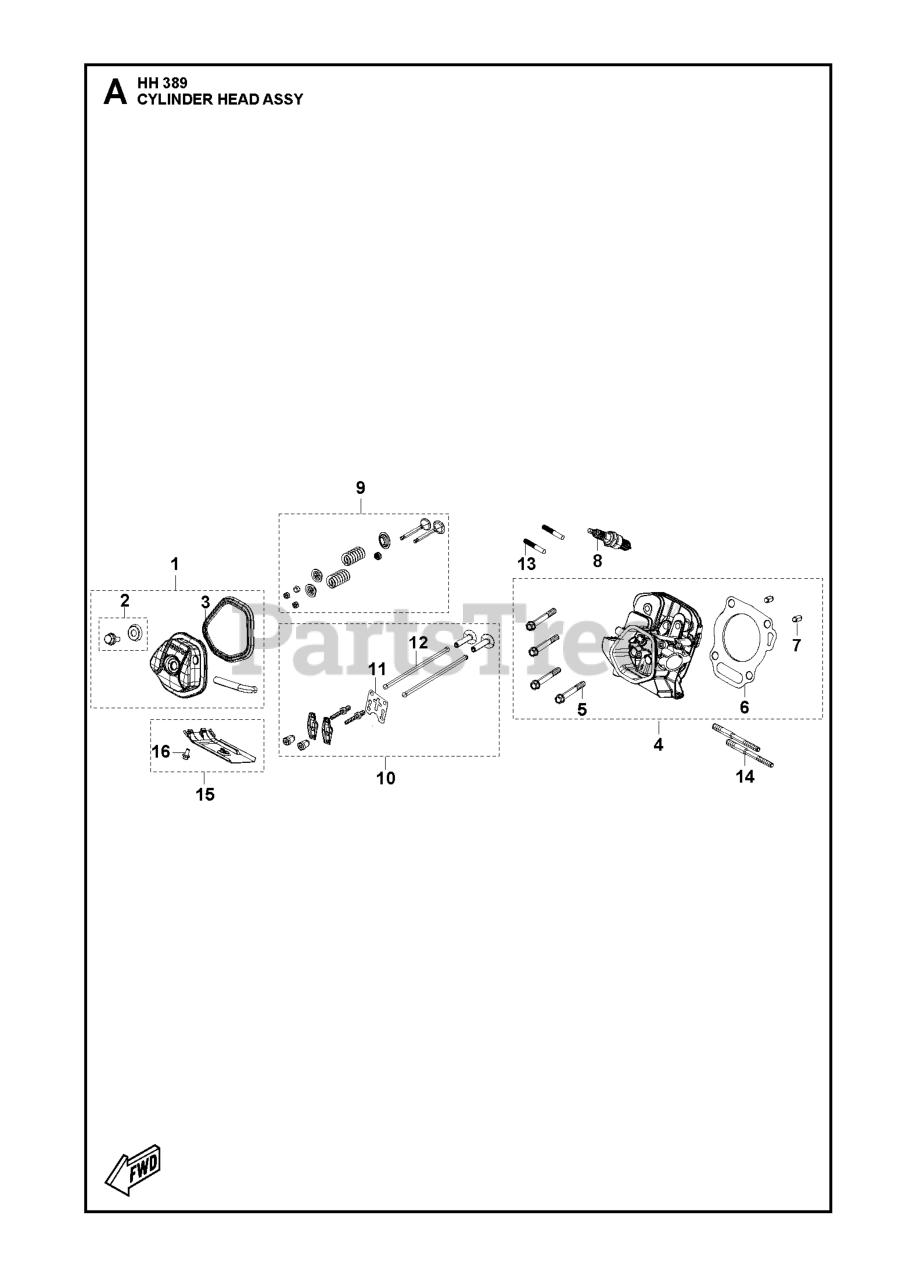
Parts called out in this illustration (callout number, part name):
1	CYLINDER COVER CYLINDER HEAD C
2	BOLT KIT
3	GASKET CYLINDER HEAD COVER GAS
4	CYLINDER HEAD KIT
6	GASKET CYLINDER HEAD GASKET
7	PIN LOCATION PIN
8	SPARK PLUG HQT-7 RESISTOR
9	VALVE KIT
10	VALVE KIT ROCKER ARM KIT
11	PLATE PUSH ROD GUIDE PLATE
12	PUSH ROD PUSH ROD SET
15	DEFLECTOR AIR DEFLECTOR KIT
16	BOLT
